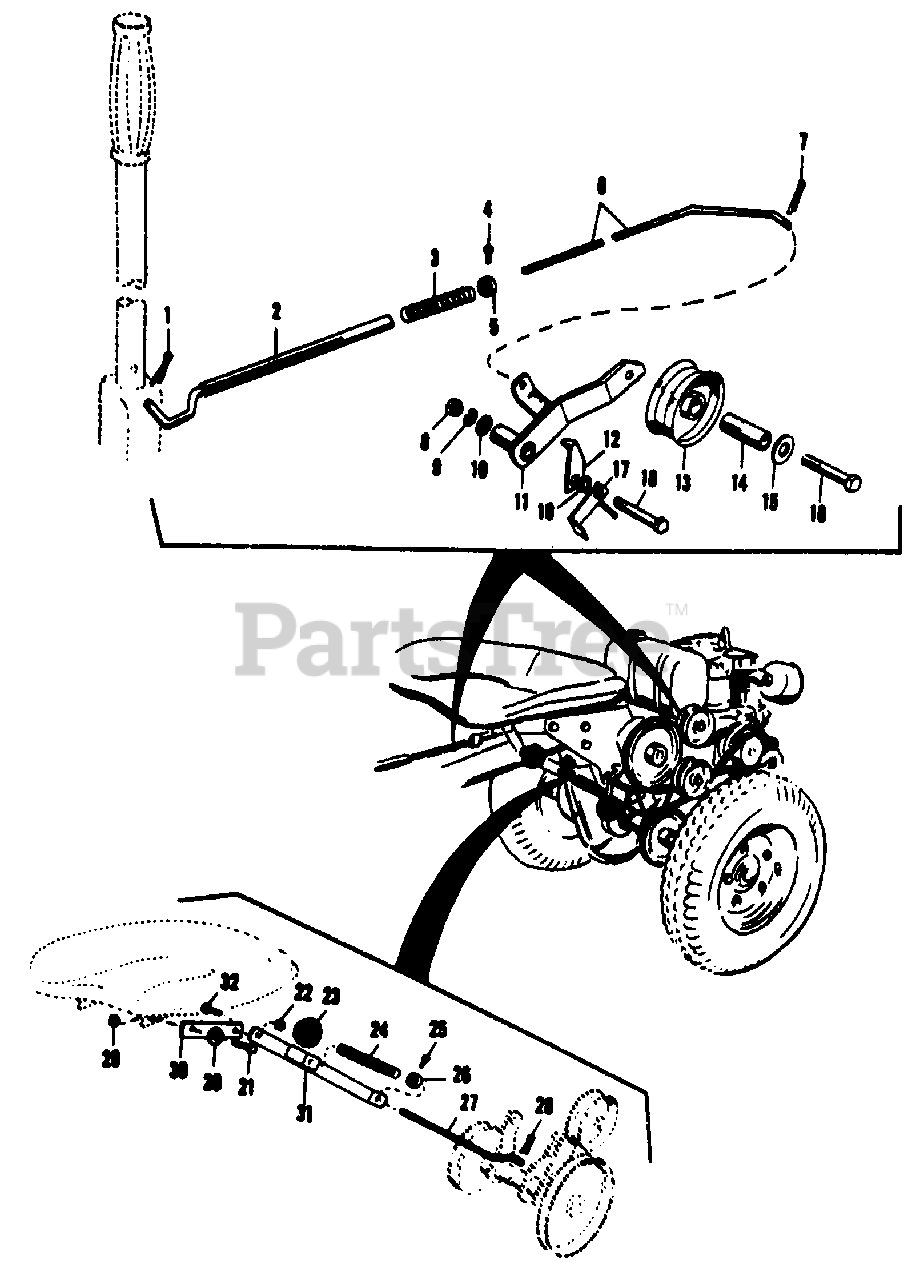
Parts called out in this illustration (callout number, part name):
2	Rod. Front Clutch Assembly
5	Collar Set
6	Rod, Rear Clutch
11	Lever Assembly Idler
12	Stop Lever
13	Pulley Idler
14	Race, Inner Bearing
17	Guide Belt
19	Pin, Lock
26	Collar Set
27	Rod, Clutch
31	Guide Assembly
